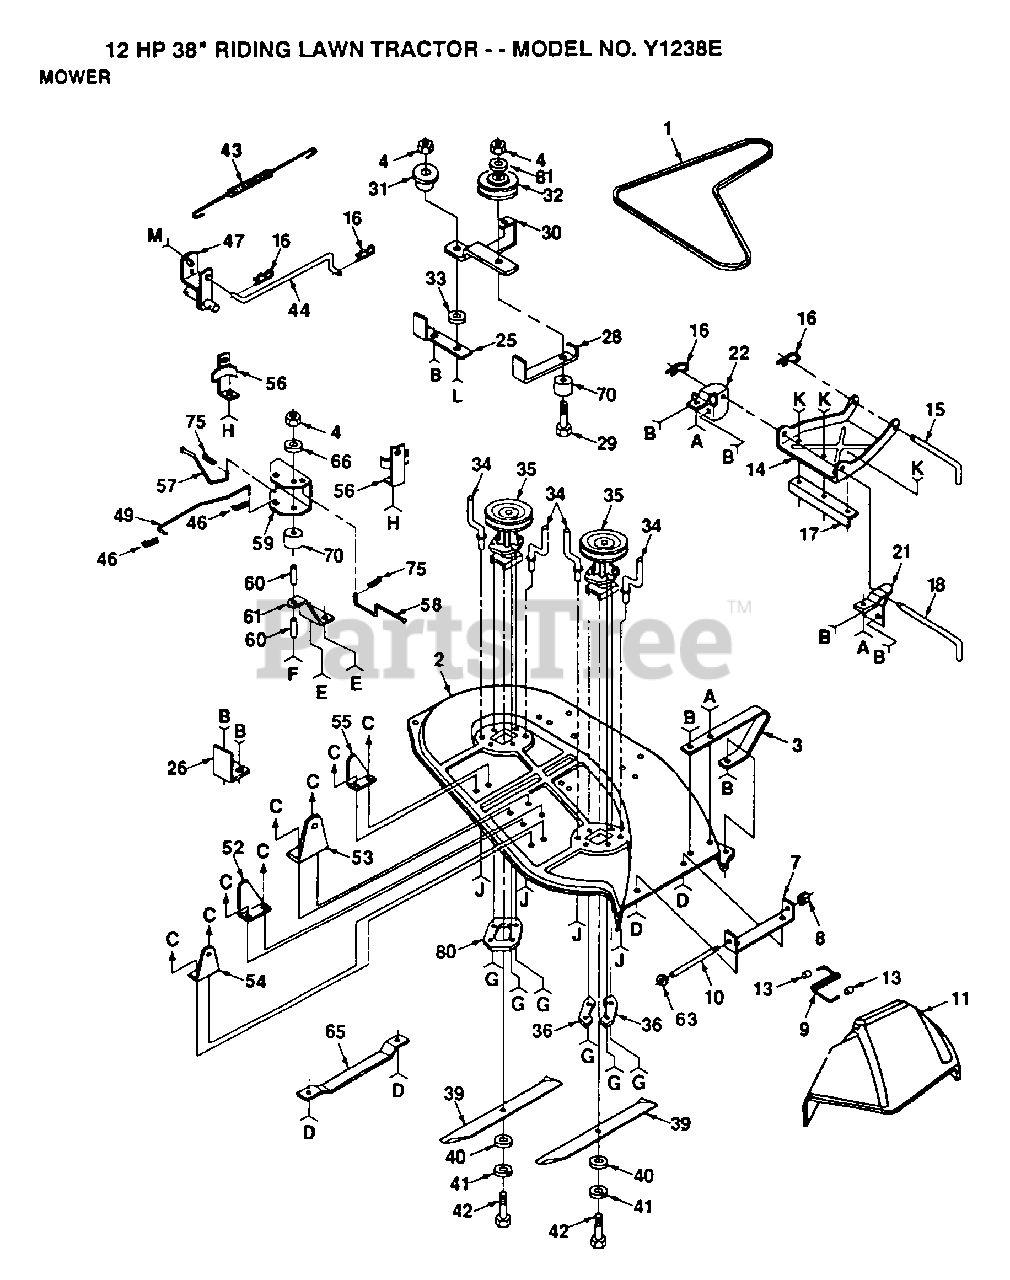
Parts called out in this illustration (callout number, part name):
1	BELT-V.79.1.MWR
8	NUT PUSH M
10	ROD-HINGE T
11	DEFLECTOR-SHLD T
13	CAP-SLEEVE LT
14	LINK.PARALLEL
15	"ROD, FRT. PARAL T"
16	SPRING.RETAINER
17	LINK STOP
18	HINGE PIN T
21	BRACKET RH LT
22	BRACKET LH T
25	SUPPORT ARM T
26	STOP T
31	SPACER RETAINER
33	"WASHER, WEAR LT"
34	BELT KEEPER LT
36	SUPPORT PLATE LT
39	"BLADE.38"" HI-LI"
40	WASHER
42	BOLT.3/8-24X1-1/2
49	ROD BRAKE LT
54	"BRKT,SUSP RH T"
56	BRAKE LT
57	"ROD, BRAKE LH LT"
58	ROD BRAKE LT
59	"BRK,BRAKE,PVT LT"
60	SPACER BRAKE LTV
61	BRACKET SUPT LTV
63	WASHER
65	RUNNER-LH M
66	WASHER
80	SUPPORT T
81	WASHER
